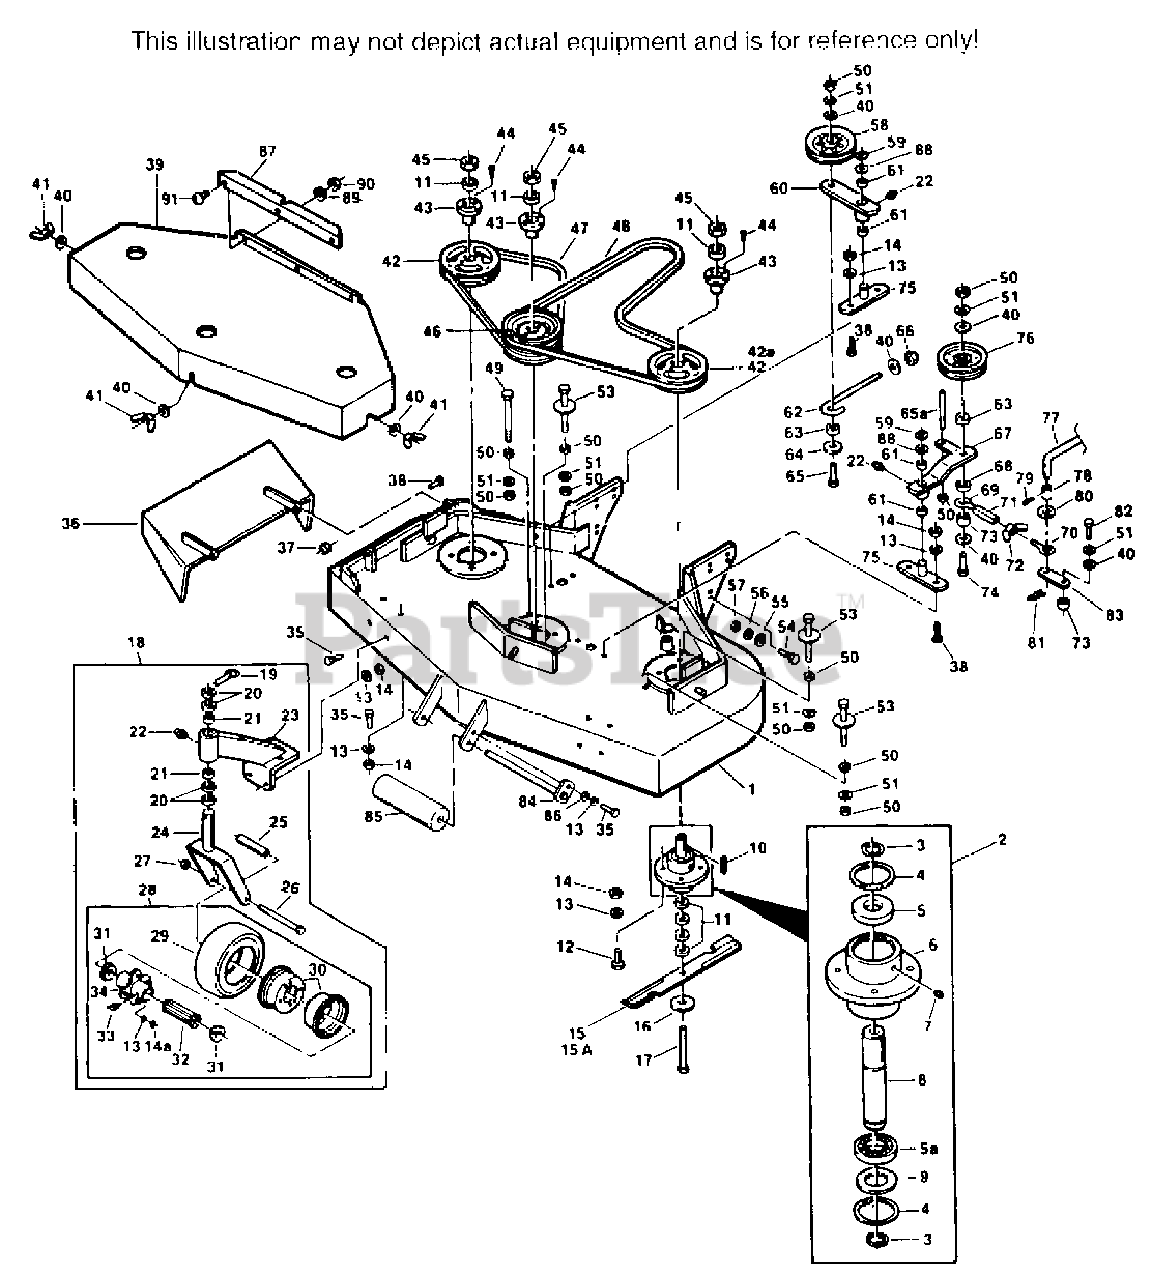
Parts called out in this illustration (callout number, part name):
1	CUTTER DECK(INCL. DECALS)
2	CUTTER SPINDLE ASSY.(INCL. 3-9)
3	RETAINING RING, 1" EXT.-INVERTED
4	RETAINING RING, 2-7/16 INT.- BASIC
5	BEARING, CUTTER SPINDLE LOWER
5A	BEARING, CUTTER SPINDLE UPPER
6	SPINDLE HOUSING
7	GREASE FITTING, STR. 5/16 SERR.
8	SPINDLE, CUTTER BLADE
9	WASHER, 1-15/16 X 2-13/32 X 16 GA.
10	KEY, 1/4 X 1/4 X 2
11	SPACER, CUTTER BLADE
15	CUTTER BLADE, 18" STD.
15A	CUTTER BLADE, 18" HIGH LIFT
16	FLAT WASHER, 5/8
17	HEX HEAD BOLT, 5/8-11 X 9-1/2
18	CASTER ASSY, COMP.(INCL. 19-28)
19	QUICK PIN
20	SPACER, CASTER YOKE, 1/2 LONG
21	BRONZE BEARING
22	GREASE FITTING, STR. 1/4-28
23	SUPPORT ASSY.(INCL. 21-22)
24	CASTER YOKE WLD.
25	SLEEVE, CASTER WHEEL BEARING
26	HEX HEAD BOLT, 1/2-13 X 5-1/2
28	WHEEL ASSY.(INCL. 13-14, 14A, 29-34)
29	TIRE ONLY, CASTER WHEEL
30	RIM PAIR, CASTER WHEEL
31	RETAINER, BEARING, CASTER WHEEL
32	ROLLER BEARING, CASTER WHEEL
33	GREASE FITTING, 45' 1/4-28
34	HUB ASSY. W/BOLTS, CASTER WHEEL
36	DISCHARGE CHUTE WLD.
37	HEX NUT, 5/16-18 ELASTIC STOP
39	BELT COVER(INCL. DECALS)
41	WING NUT, 3/8-16
42	PULLEY(INCL. 43-44)
43	TAPER HUB
46	PULLEY, DOUBLE(INCL. 43-44)
47	BELT, RH BLADE DRIVE
48	BELT, BLADE DRIVE
51	LOCKWASHER, 3/8 SPRING
53	BELT GUIDE
57	HEX NUT, 1/2-13 ELASTIC STOP
58	PULLEY
59	RETAINING RING, 3/4" EXT.- "E"
60	IDLER ARM ASSEMBLY(INCL. 22 & 61)
61	BRONZE BEARING
62	J ROD, IDLER PULLEY
63	SPACER
64	WASHER, 3/8 X 1-1/2 X 16 GA.
66	HEX NUT, 3/8-16 ELASTIC STOP
67	IDLER ARM(INCL. 22 & 61)
68	SPACER
69	EYEBOLT, LH
70	EYEBOLT, RH
71	TURNBUCKLE
72	WING NUT, 5/16-18
73	SLEEVE, CAM CLUTCH
75	IDLER PIVOT
76	PULLEY, IDLER
77	BLADE CLUTCH ROD
78	SLEEVE, CLUTCH ROD
80	FLAT WASHER, 33/64 X 1 X 16 GA.
81	HARI PIN, LARGE
83	CAM LINK
84	ROLLER SHAFT
85	GUIDE ROLLER
87	BELT COVER SKIRT
88	FLAT WASHER, 49/64 X 1-1/4 X 16 GA.
91	MACHINE SCREW, 1/4-20 X 1/2 SLT. TRUSS HD.
